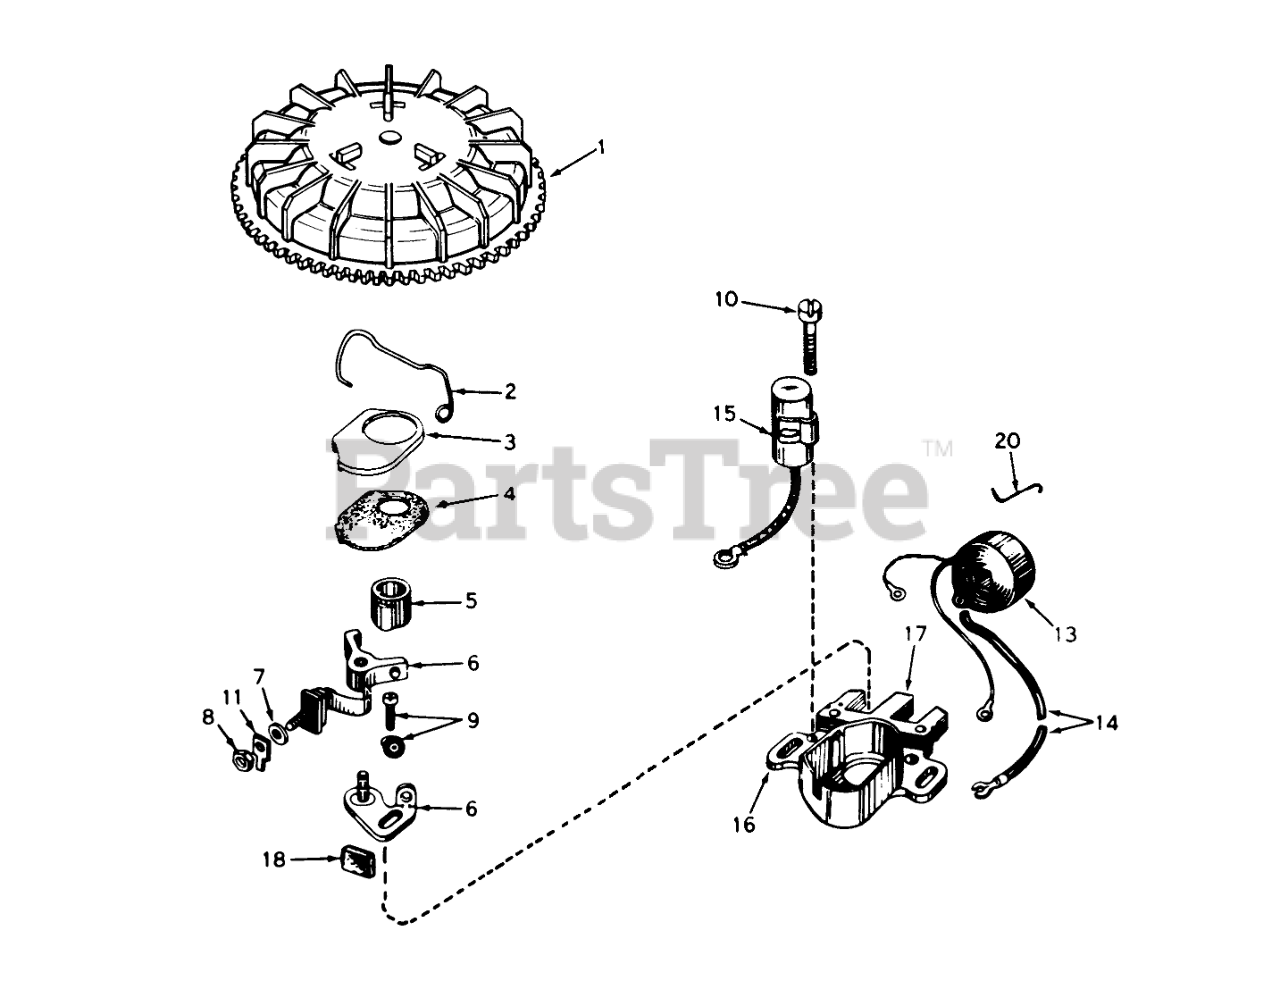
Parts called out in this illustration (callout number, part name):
1	Flywheel (Incl. Ref. #3 & 4)(used on type 1583, 1583A & 1583B)
1	Flywheel (Incl. Ref. #3 & 4)(used on type 1585, 1585A & 1585B)
2	Spring Breaker Box
3	Cover-Dust
4	Gasket, Dust Cover
5	Cam, Breaker
6	Breaker Assy.
9	Breaker Screw
10	Condenser Screw
11	Terminal, Ground
13	Coil Assembly (Incl. Ref. #14)
14	Wire, Lead
15	Condenser
16	Core & Plate
17	Stator Assembly (Incl. Ref. #2, 3, 4, 6 thru 16, 18 & 20)
18	Felt,Cam Wiper
20	Clip, Coil
